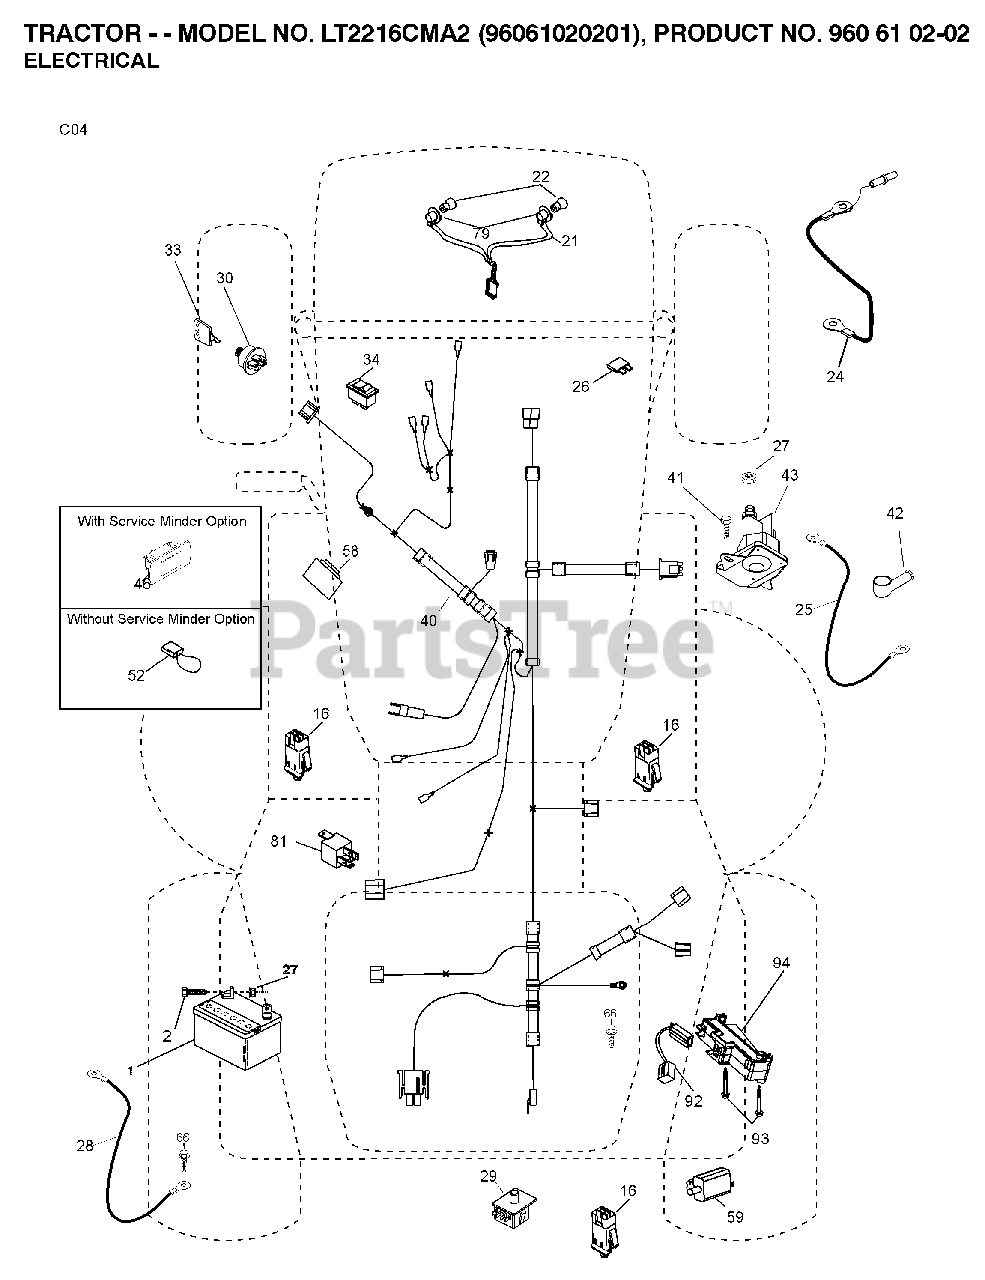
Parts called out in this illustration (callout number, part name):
1	REPL BY 532 12 38-99
16	SWITCH INTERLOOK PUSH-IN
21	HARNESS ASSY LIGHT
22	LIGHTBULB
24	BATTERY CABLE GT
25	CABLE BATTERY
26	FUSE 20AMP
27	NUT
28	CABLE GROUND
29	SWITCH.SEAT.DP W/RAMPS
30	SWITCH.IGN.DELTA.W.LGH.ROS
33	KEY.CHAIN.BLISTER.PACK.GEN.INT
34	SWITCH LT
42	TERMINAL COVER
43	SOLENOID.W/BRASS.PLUNG
58	BUZZER
79	BULB HOLDER ASM.
81	RELAY.ASSY.T
92	HARNESS.PIGTAIL.CONSLE
93	SCREW.PLASTITE
94	MODULE.REVERSE.ROS
